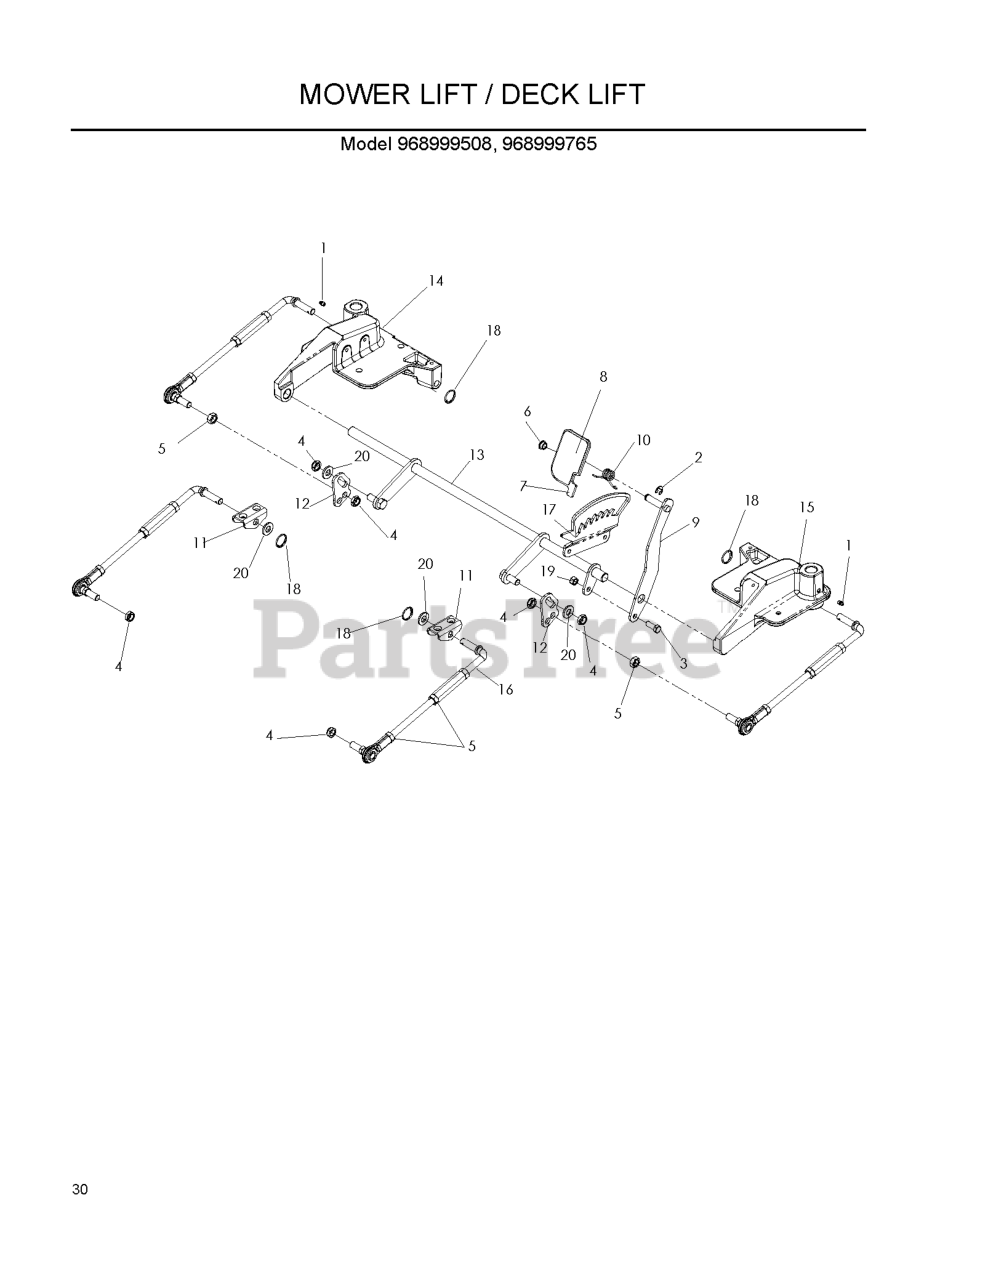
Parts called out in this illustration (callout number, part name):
2	E-RING 1/2 (2 2)
3	HEX BOLT 3/8 X 1"
4	JAM NUT 1/4C (2 2 PW01)
5	NUT 1/2-20 HEX JAM ZD
6	BUSHING, FLANGED NYLON
7	FOOT PEDAL
8	FOOT PAD, NON-SLIP
9	LIFT FOOT, LEVER WELDED
10	SPRING, PEDAL, LIFT
11	BRACKET, DECK HANGER
12	CONNECTOR, DECK LIFT
13	LIFT SHAFT WLDT
14	CASTING, CASTER, LT
15	CASTING, CASTER, RT
16	LINKAGE ASM, LIFT
17	HEIGHT PLATE, DECK
19	NUT 3/8-16 NYLOC
20	WASHER 1/2" FLAT
